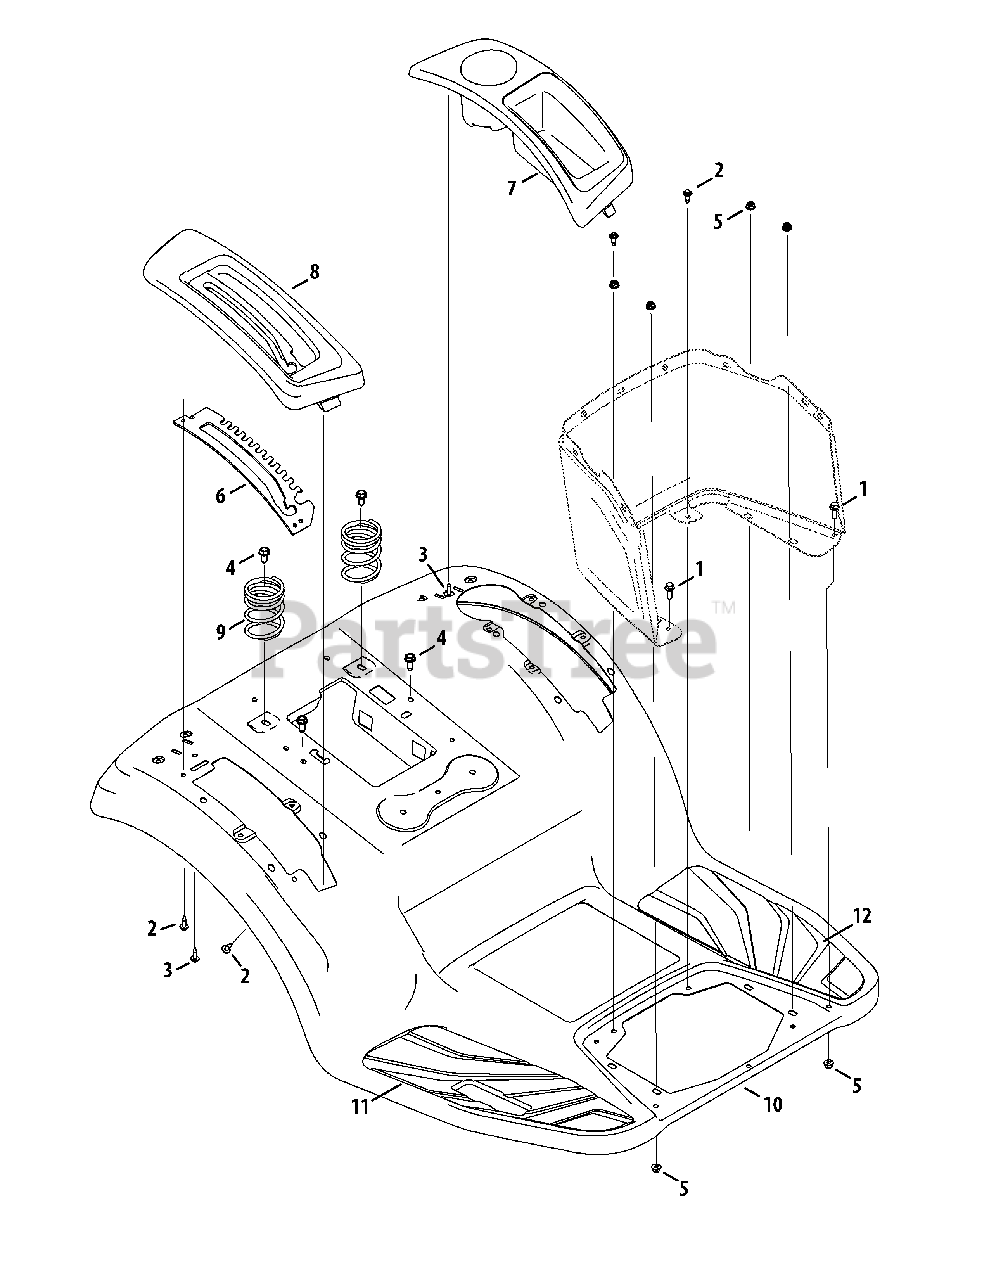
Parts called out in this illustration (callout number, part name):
1	Hex flange Screw, 1/4-20 x .75
2	Screw, M6-1 x .625
3	Screw, 1/4-10 x .75
4	Screw, Self-tapping, 3/8-16, 0.750,
5	Nut, Flange Lock, 1/4-20, Nylon
7	Cover, LH
8	Cover, RH, Electric PTO
9	Compression Spring, 2.50 x 3.951 x .207
10	Fender
11	Pad, Foot, RH
12	Pad, Foot, LH
